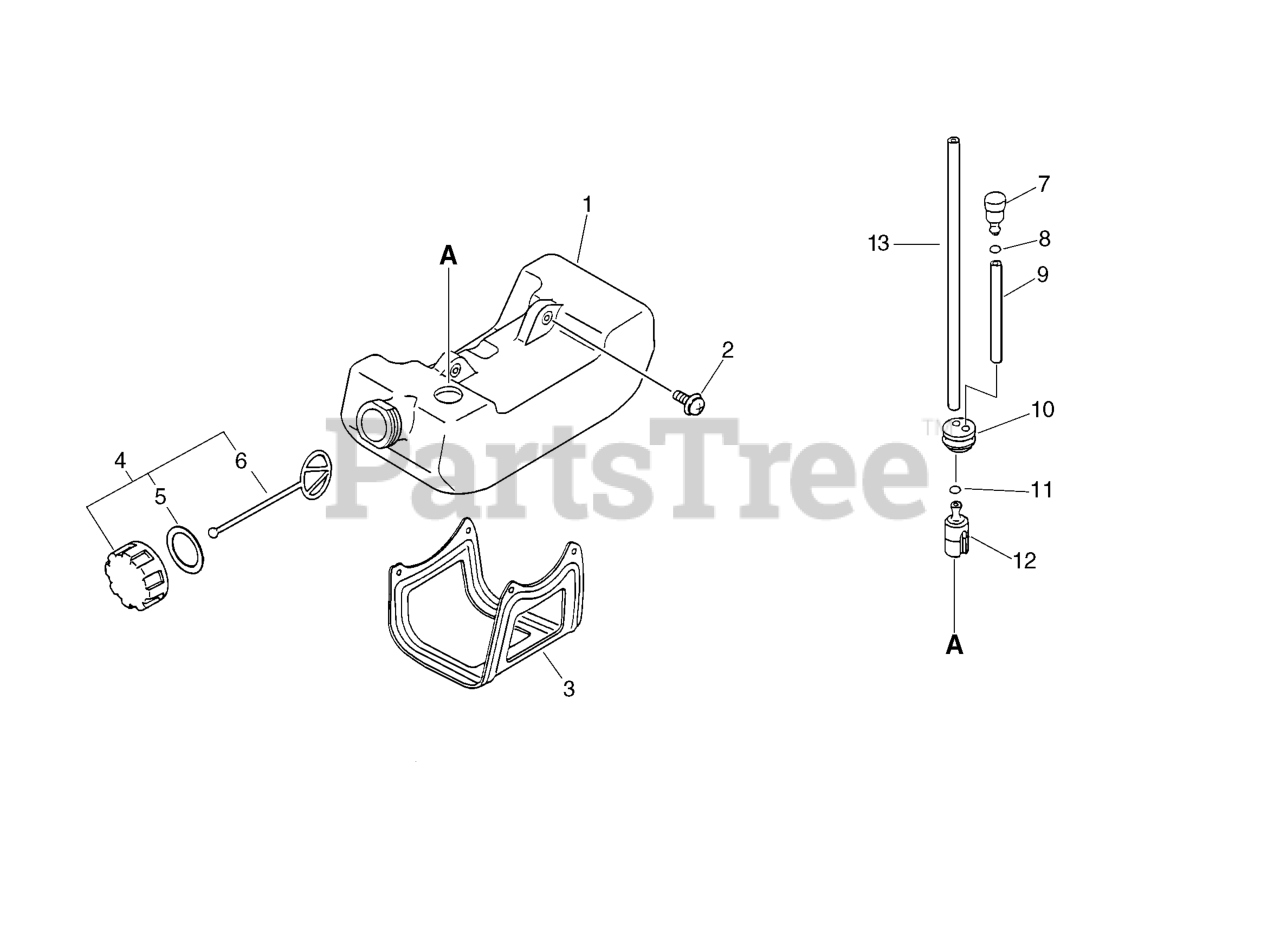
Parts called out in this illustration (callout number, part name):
1	TANK, FUEL
2	SCREW 5×16
3	GUARD, FUEL TANK
4	CAP ASSY, FUEL
5	GASKET, FUEL CAP
6	CONNECTOR, CAP
7	VENT ASSY
8	CLIP 5.5
9	PIPE, FUEL 3×5×70 BLACK
10	GROMMET, FUEL
11	CLIP 6 MM
12	FILTER, FUEL
13	PIPE, FUEL 3×5×180
